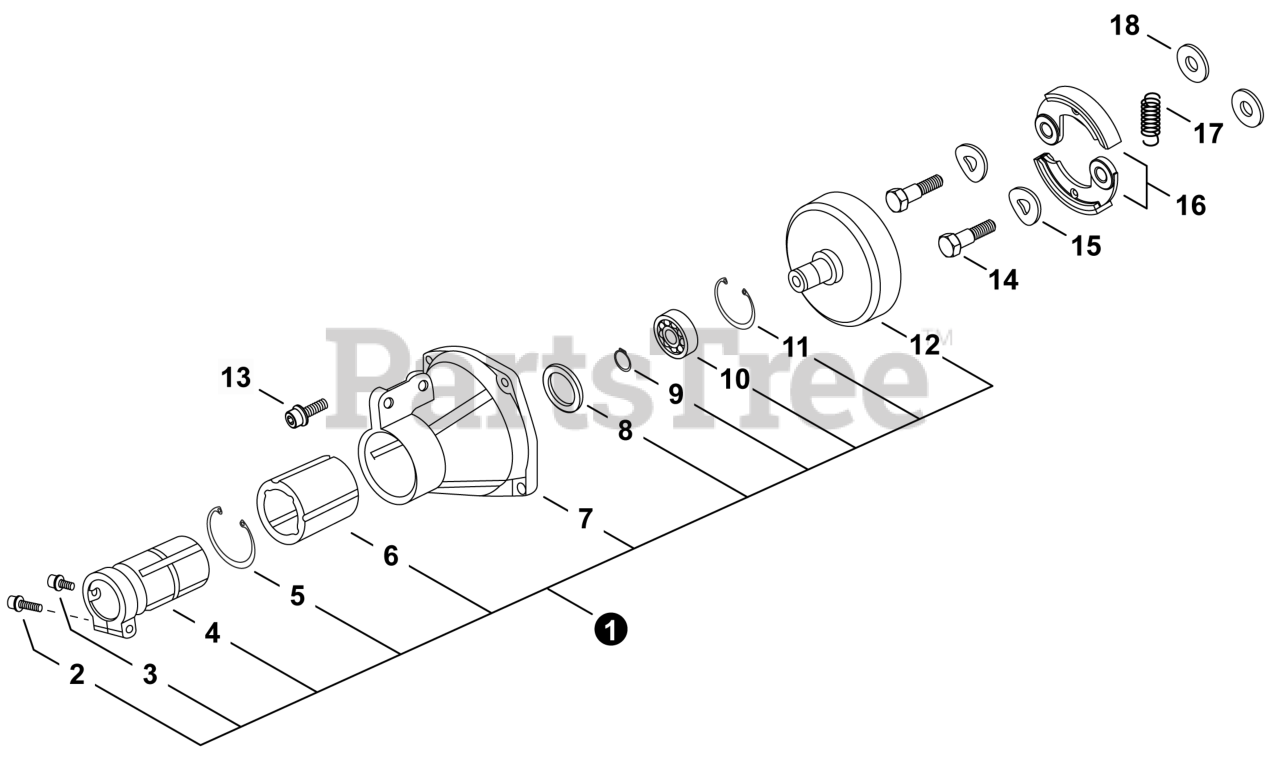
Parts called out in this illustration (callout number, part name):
1	CASE ASSY, CLUTCH
2	BOLT 5x25
3	BOLT 5x12
5	RING, SNAP
6	CUSHION
7	CASE, CLUTCH
9	RING, SNAP
10	BEARING, BALL
11	RING, SNAP
12	DRUM, CLUTCH
14	BOLT, CLUTCH
15	WASHER 10.2x18x1.0
16	CLUTCH SHOE SET
17	SPRING, CLUTCH
18	WASHER 8.2x17x1.6
